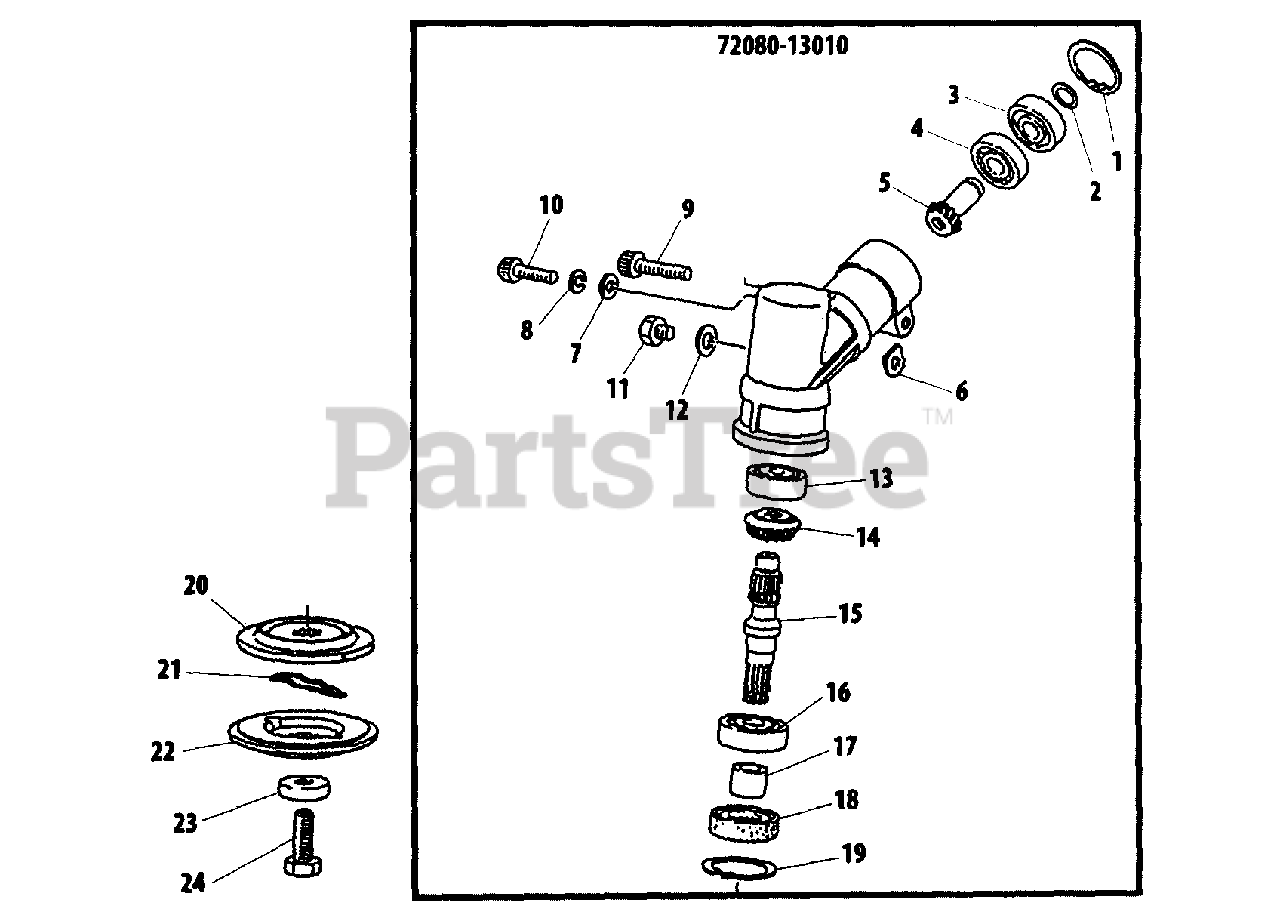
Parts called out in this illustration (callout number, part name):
1	RING, RETAINING - 28
2	RING, RETAINING
3	BEARING, BALL - 6001ZZ
4	BEARING, BALL - 6001
5	GEAR - SHAFT
6	SHIM
7	WASHER - 6
8	LOCKWASHER - 6
9	SCREW - 6X28
10	SCREW - 6X12
11	BOLT - 6X10
12	WASHER
13	BEARING, BALL - 6000DDU
14	GEAR - BEVEL
15	GEAR - SHAFT
16	BEARING, BALL - 6202
17	COLLAR
18	SEAL, OIL
19	RING, RETAINING - 35
20	HOLDER (A)
21	SLIDE PIN
22	HOLDER (B)
23	GUARD
24	BOLT - 10 -- LEFT HAND
72080-13010	GEAR CASE ASSY
